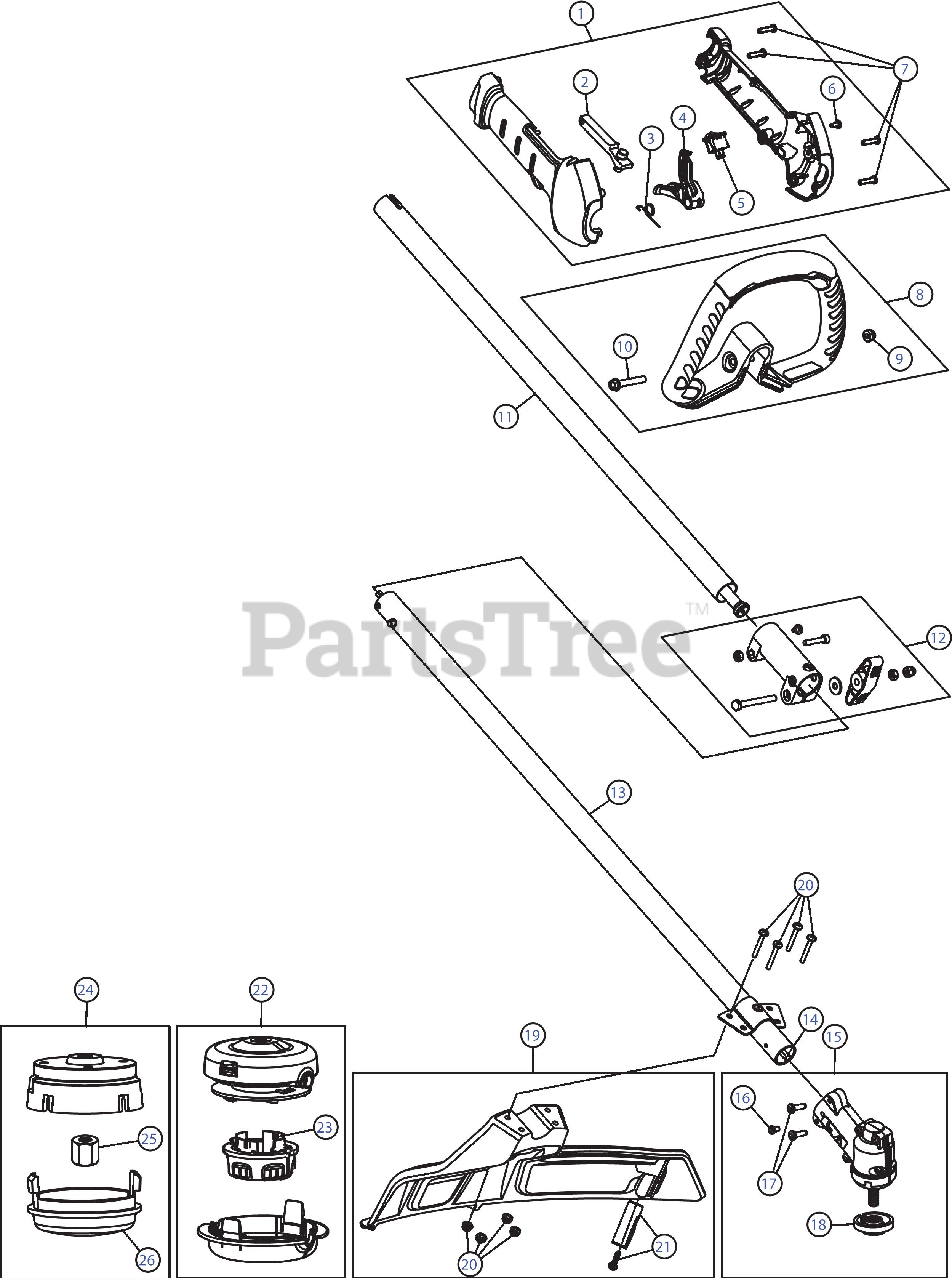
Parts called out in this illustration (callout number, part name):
1	Throttle Housing Assembly (Incl. 2
2	Throttle Lockout
3	Throttle Trigger Spring
4	Throttle Trigger
5	Switch Assembly
6	Grip Anti-Rotation Screw
8	D-Handle Assembly (Incl. 9 & 10)
11	Upper Drive Shaft Housing
12	Split Boom Coupler
13	Lower Drive Shaft Housing Assembly (Incl. 14)
14	Lower Flexible Drive Shaft
15	Gearbox Assembly (Incl. 16 - 18)
16	Anti-Rotation Screw
17	Gearbox Mounting Hardware
18	Cutting Head Driver
19	Shield Assembly (Incl. 20 & 21)
20	Shield Mounting Screws and Nuts
21	Blade Assembly
22	Cutting Head Assembly
24	Aero Flex Cutting Head (Incl. 25 & 26)
26	Aero Flex Cap
